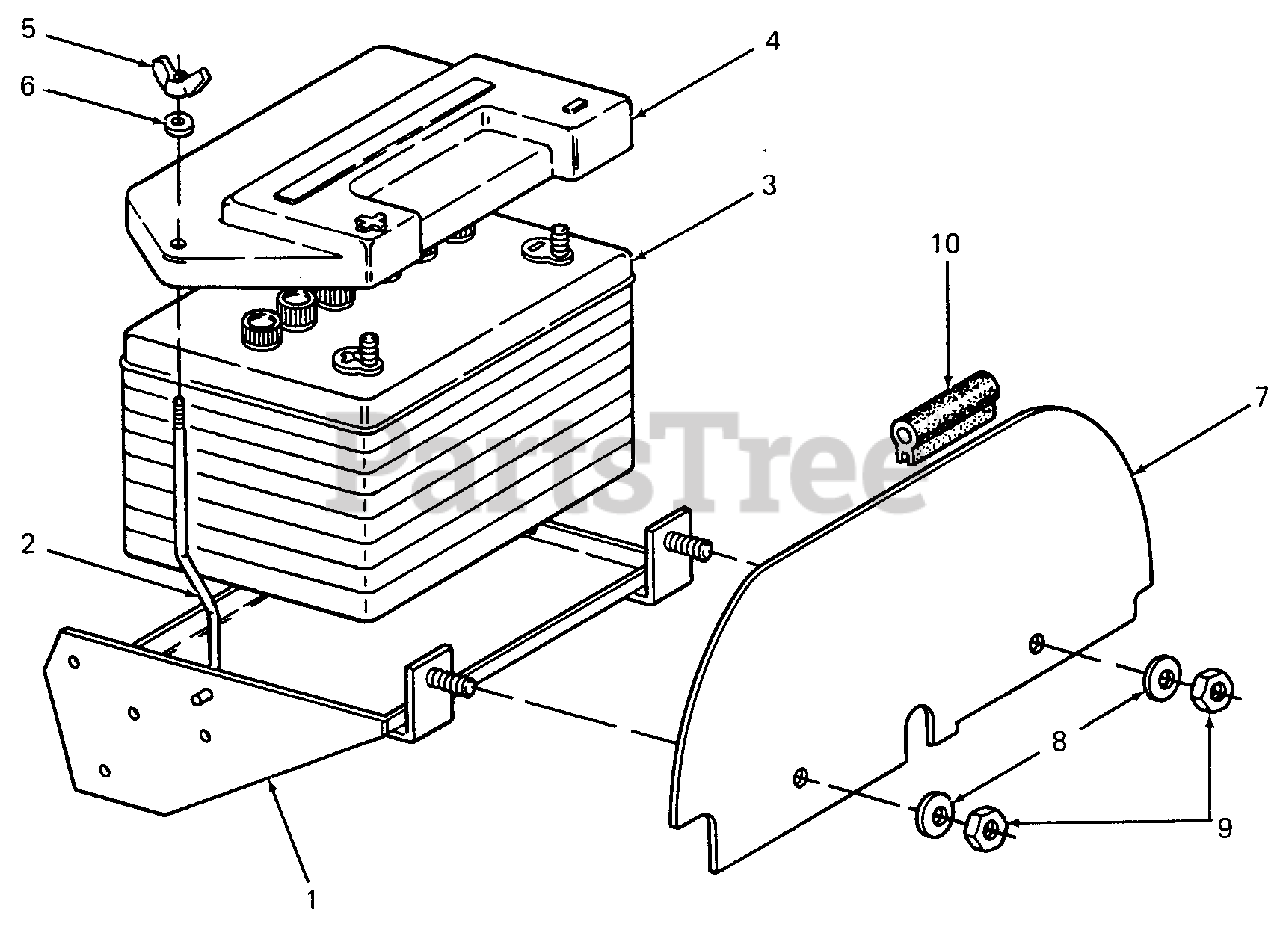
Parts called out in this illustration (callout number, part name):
1	Tray, Battery
2	Rod, Battery Hold Down
4	Cover, Battery w/Product Graphic
5	Nut, Wing, 1/4-20
6	Washer, Flat, .281 X .50 X .063 Thk
7	Baffle, Heat
8	Washer, Bell, .265 X .75 X .062 Thk
9	Nut, Hex Patch Lock, 1/4-20
10	Seal, Heat Baffle, 22.0 Lg
